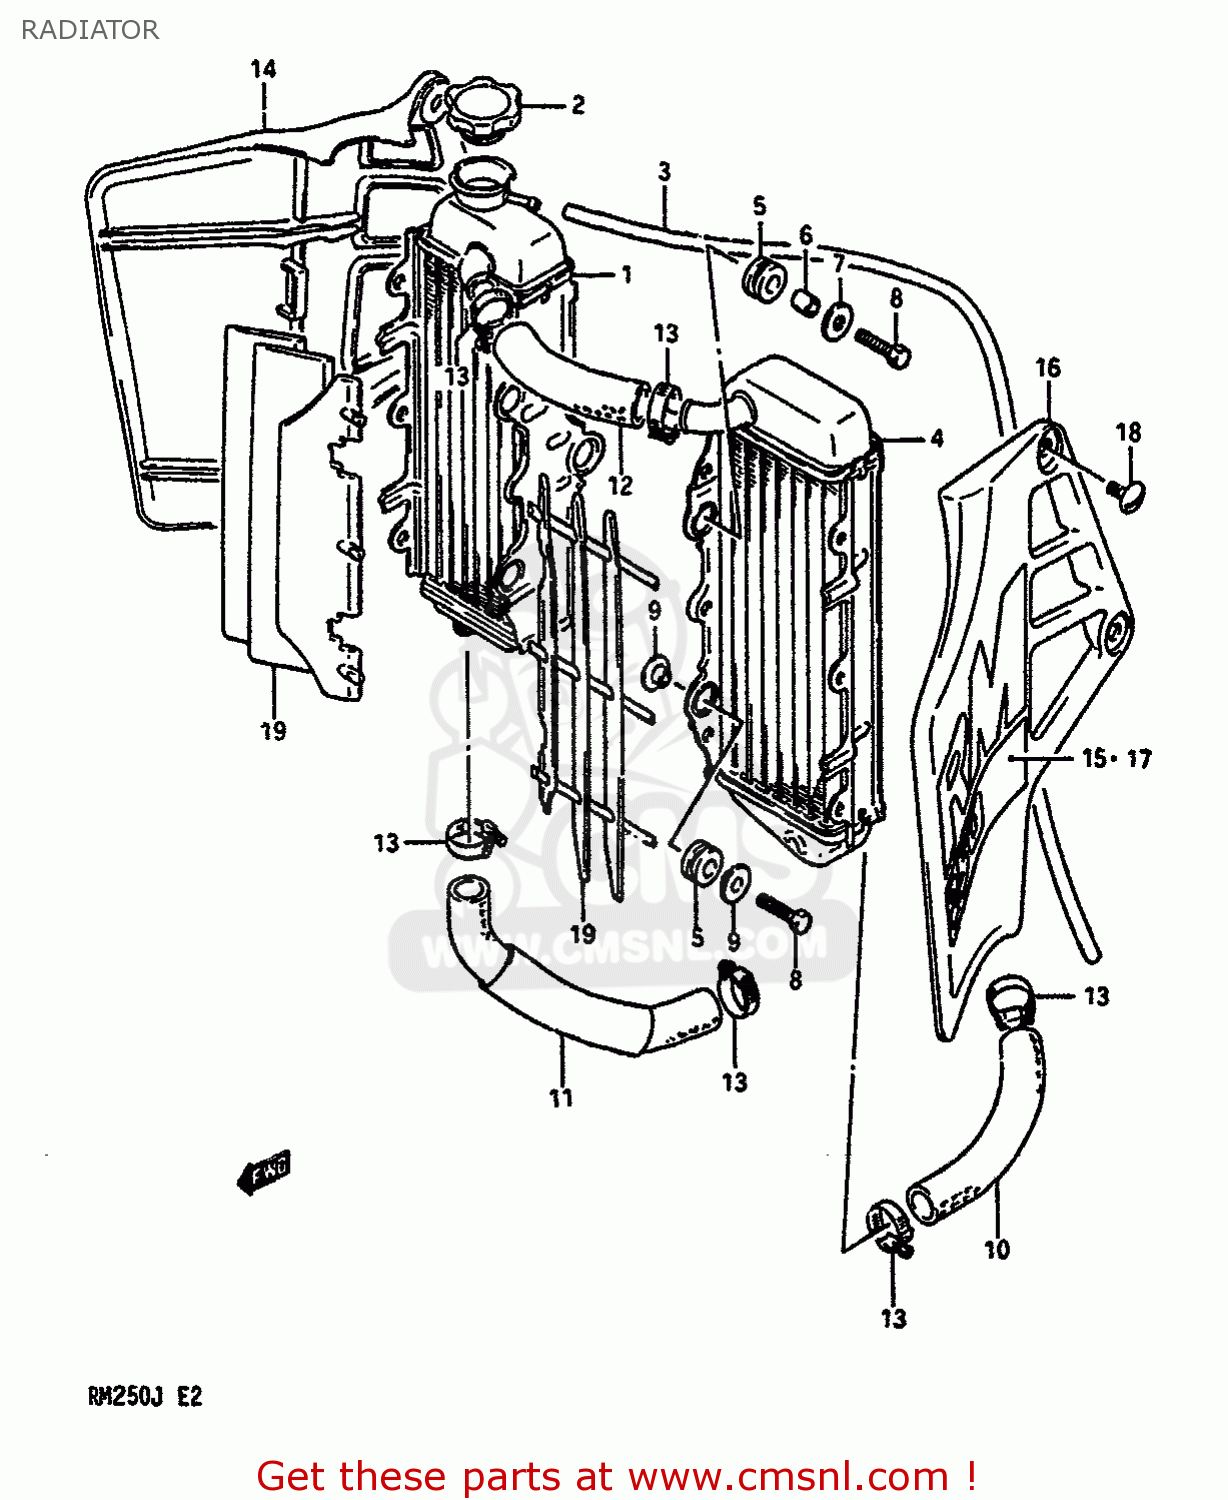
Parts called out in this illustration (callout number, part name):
1	RADIATOR COMP,WATER,RIGHT
2	CAP,RADIATOR 1.1
3	HOSE
4	RADIATOR,WATER,L
5	CUSHION,RADIATOR LWR
6	SPACER(6.5X10.5X12)
7	WASHER (6.5X24X1.6)
8	BOLT
9	WASHER,RDTR SPRT
10	HOSE,RADIATOR INLET
11	HOSE,RADIATOR OUTLET
12	HOSE,RADIATOR
13	CLAMP
14	COVER,RADIATOR,R
15	EMBLEM,RADIATOR COVER
16	COVER,RADIATOR,L
17	EMBLEM,RADIATOR COVER
18	SCREW (6X12)
19	LOUVER,RADIATOR
